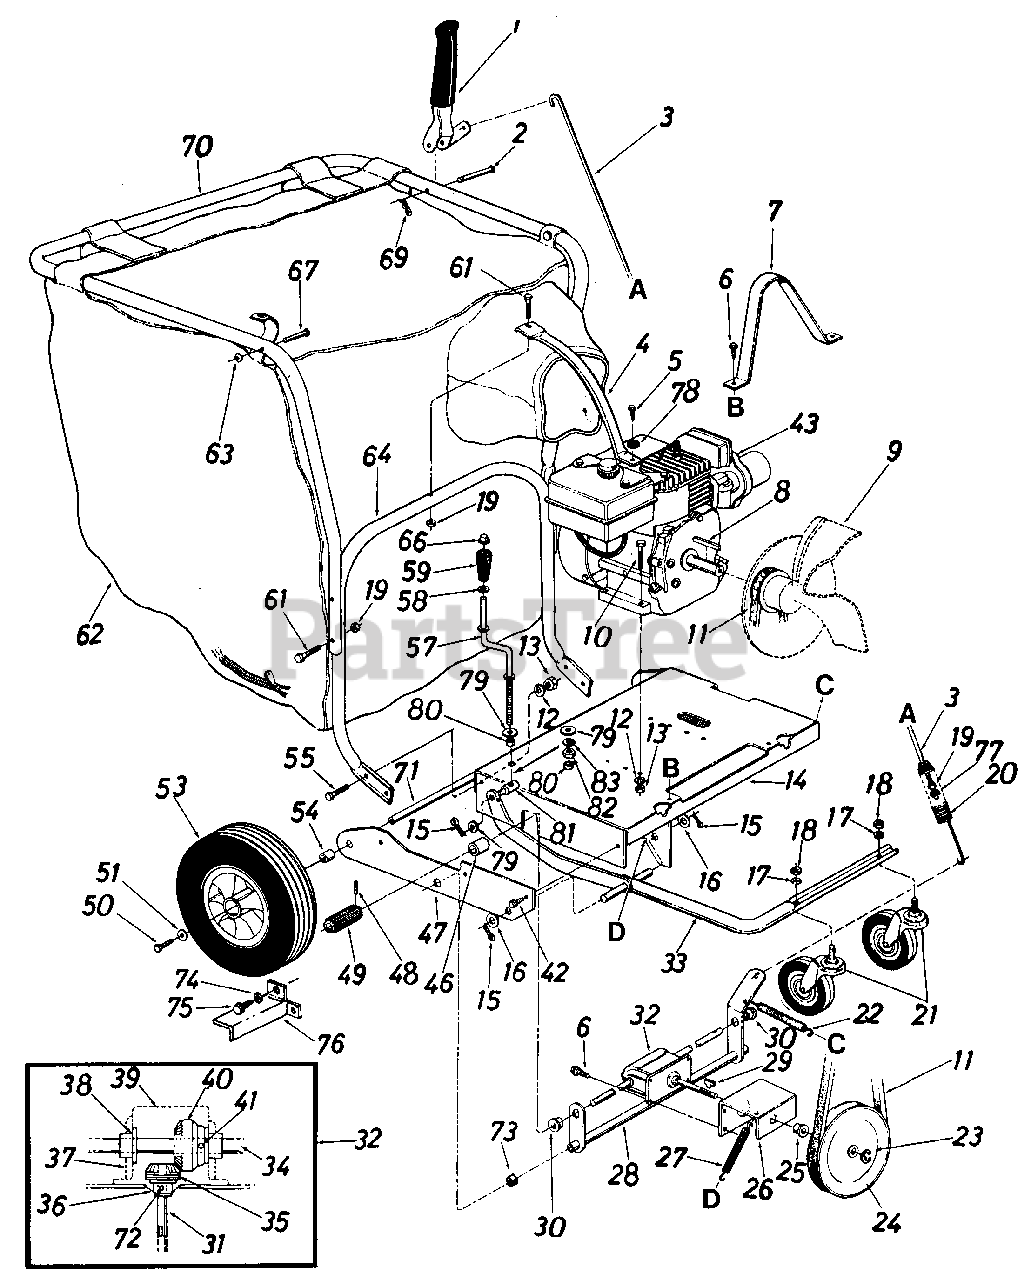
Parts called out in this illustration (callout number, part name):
1	Clutch Grip Ass'y.
2	Clevis Pin .375" Dia. x 1.88"
3	Clutch Rod 32" Lg.
4	Handle Brace (Painted)
5	Part of Engine
6	Hex Wash. Hd. AB-Tap Scr. 1/4" x .62" Lg.
10	Hex Bolt 5/16-18 x 1.5" Lg.
11	"V"-Belt
12	L-Wash. 5/16" I.D.
13	Hex Nut 5/16-18 Thd.
16	Fl-Wash. .63" I.D. x 1.25" O.D.
17	L-Wash. 1/2" I.D.
18	Hex Nut 1/2-13 Thd.
19	Hex Cent. L-Nut 1/4-20 Thd.
20	Extension Spring .78" O.D. x .75" Lg.
21	Swivel Caster Wheel 5" Dia. x 1.25"
22	Extension Spring .38" O.D. x 7.50" Lg.
23	Snap "E"-Ring .50" Dia. Shaft
24	"V"-Pulley 5/8" x 6.50" O.D.
25	Flange Bearing .502" I.D.
28	Clutch Brac~et Ass'y.
29	#2 Woodruff Key 3/32" Dia. x .81 " Lg.
30	Hex Flange Bearing Bronze .625" I.D.
31	Pinion Shaft .50" Dia. x 5"
32	Gear Box Ass'y. Comp.
35	Bevel Gear .50" I.D. x 14 Teeth
36	Flange Bearing .503" I.D.
37	Gear Box
38	Flange Bearing .630" I.D.
39	Gear Box Cover
40	Bevel Gear .62" I.D. x 28 Teeth
41	Spring Pin Spiral 3/16" Dia. x 1.25" Lg.
42	Hex Wash. Hd. AB-Tap Scr. 5/16" x .75" Lg.
43	Engine
46	Spacer.63" I.D. x .88" O.D. x .56" Lg.
49	Dive Pinion
50	Hex Locking Bolt 5/16-24 x .62" Lg.
51	Fl-Wash. .34" I.D. x .87" O.D.
53	Wheel Ass'y. Comp. 12" x 3" (Incl. Ball Bearings)
54	Pacer .63" I.D. x 1.0" O.D. x .94" Lg. (675, 685, 687)
55	Hex Bolt 5/16-18 x .75" Lg.
57	Height Adjustment Crank
58	Fl-Wash. .385" I.D. x .62" O.D.
59	Crank Knob
61	Hex Bolt 1/4-20 x 1.75" Lg.
62	Vacuum Bag--Felt
63	Push Speed Nut .25" Dia. Stud
66	Push Nut 3/8" Dia.
67	Stud Pin .250" Dia. x 1.75"
69	Internal Cotter Pin 3/8" Dia.
70	Upper Handle (Painted)
71	Rear Axle
72	Spring Roll Pin 5/32" Dia. x 1 . 1 2
73	Spacer .82" I.D. x 1.0" O.D. x .305 Lg.
74	L-Wash. .265" I.D.
75	Hex Self-Tap Scr. 1/4" x 3/8" Lg.
78	Belleville Washer
79	Fl-Wash. .35" I.D. x .87" O.D.
80	Spacer .38" I.D. x .50" O.D. x .18"Lg.
81	Ferrule 3/8-8 x .38" Dia.
82	Hex Nut 3/8-8 Thd.
83	L-Wash. 3/8" I.D.
